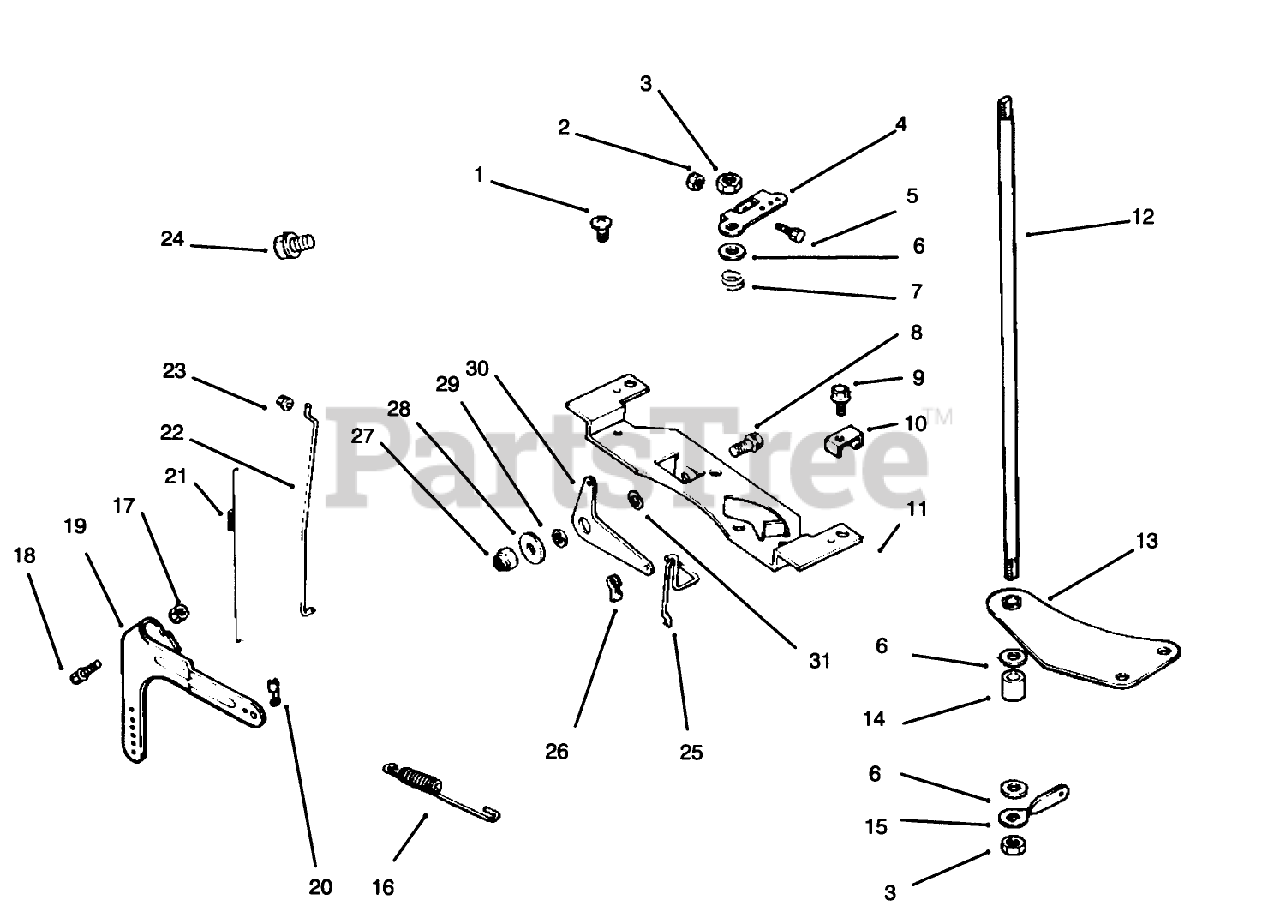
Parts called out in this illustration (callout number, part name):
4	Lever-Throttle Control
5	Screw-HHF M4x0.7x28 (Only On: 72042, 72063, 72062, 72043)
6	Washer
7	Spring-Throttle Shaft
11	Bracket-Control
12	Shaft-Throttle
13	Bracket-Throttle Shaft
15	Lever-Throttle Control
16	Spring-Governor
19	Lever-Governor
20	Bushing-Linkage
21	Spring-Linkage
22	Linkage-Throttle (Only On: 72103)
23	Bushing
25	Linkage-Choke
26	Bushing-Linkage
28	Washer
30	Lever-Choke
31	Washer
